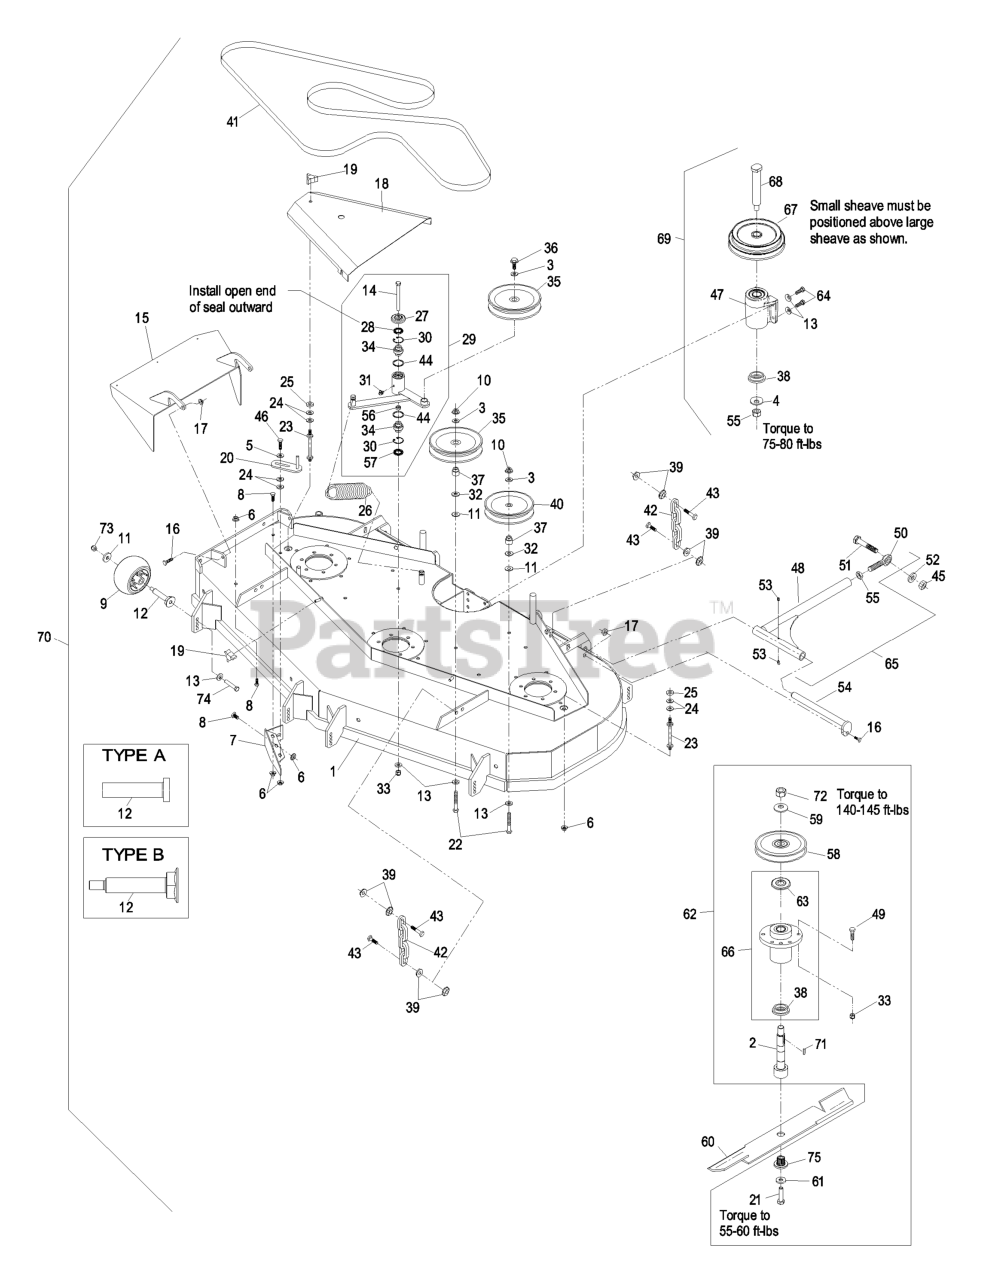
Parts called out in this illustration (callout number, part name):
1	ASM,DECK W/DECALS XP604
2	KIT, SPLINED SPINDLE 103-
3	WASHER-FLAT
4	WASHER-SPRING
5	WASHER-SPRING
7	WLD,BAFFLE DISCHARGE
8	SCREW-HH
9	ROLLER-SCALP, ANTI
10	NUT-HHF, WHIZ
12	BUSHING-ROLLER
13	WASHER-BELLEVILLE
14	SCREW-HH
15	WLD,CHUTE XP604
16	SCREW-HH
17	NUT-LOCK, NI
18	SHIELD,BELT
19	KNOB-3 PRONG
20	GUIDE-BELT
21	SCREW-HH
22	SCREW-HH
23	STUD-SHIELD, BELT (SHORT)
24	WASHER-FLAT
27	GUARD-TOP
28	SEAL-LIP, SINGLE
29	KIT,DECK IDLER LZ/XP
30	RING-SNAP
31	FITTING-GREASE, 90 DEG
32	WASHER-FLAT
33	NUT-LOCK, NI
34	BEARING-SPHERICAL
36	SCREW-HHF
37	BUSHING-IDLER
38	SPACER-GUARD, BOTTOM
40	PULLEY-IDLER
41	BELT,BLADE DRIVE
42	CHAIN-LIFT, DECK
43	SCREW-HH
45	NUT-HEX
46	SCREW-HH
49	SCREW-HH
50	BALLJOINT-SPHERICAL
51	SCREW-HH
52	WASHER-LOCK
53	FITTING-GREASE
54	PIN-STRUT
55	NUT-HEX
57	SEAL-LIP, DOUBLE
58	SHEAVE,BLADE DRIVE 6.30
61	WASHER-SPRING
62	ASM, CUTTER HSG COMPLETE
63	GUARD-BEARING, TOP
64	SCREW-HH
65	ASM,DECK STRUT XS 60
66	KIT, CUTTER HOUSING
67	SHEAVE, JACKSHAFT DOUBLE
68	JACKSHAFT
69	KIT,JACKSHAFT 60/72-3750
70	Asm, Deck Complete
72	NUT-HH
73	NUT-HHF, WHIZ
74	SCREW-HH
75	BUSHING,SPLINED
